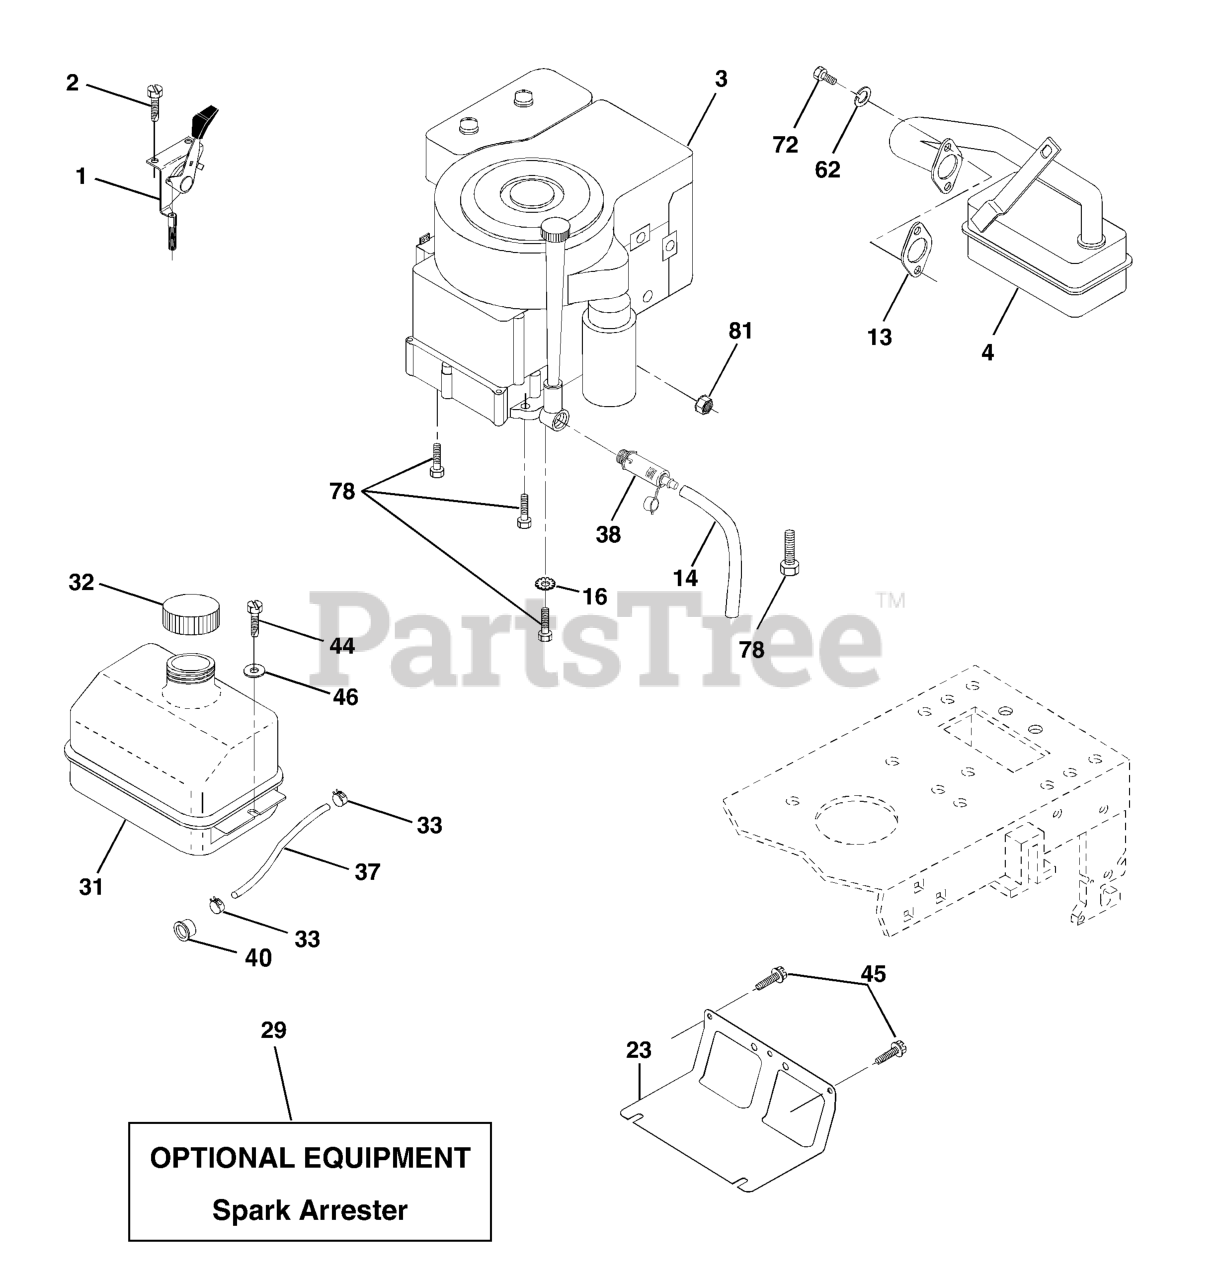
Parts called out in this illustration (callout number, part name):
1	CONTROL.THROTTLE/CHOKE.BLACK
2	SCREW LT
4	MUFFLER.SINGLE.B&S.10-12HP
13	REPL BY 532 27 22-93
14	TUBE, DRAIN OIL ASM.
16	LOCKWASHER
23	SHIELD.BROWNING.DBR.GUARD
29	KIT.SPARK ARRESTOR 794945 B&S
31	TANK FUEL LT
32	FUEL CAP
33	HOSE CLAMP
37	LINE.FUEL.20
38	PLUG, OIL DRAIN EASY
40	BUSHING.SNAP.NYL.BLK.
44	SCREW HEXWSHR 1/4-20X3/4
45	SCREW, 3/8-16X3/4
46	WASHER
62	WASHER.LOCK.HVY.HLCL.SPR.5/16
72	SCREW
78	SCREW.3/8-16
81	NUT
